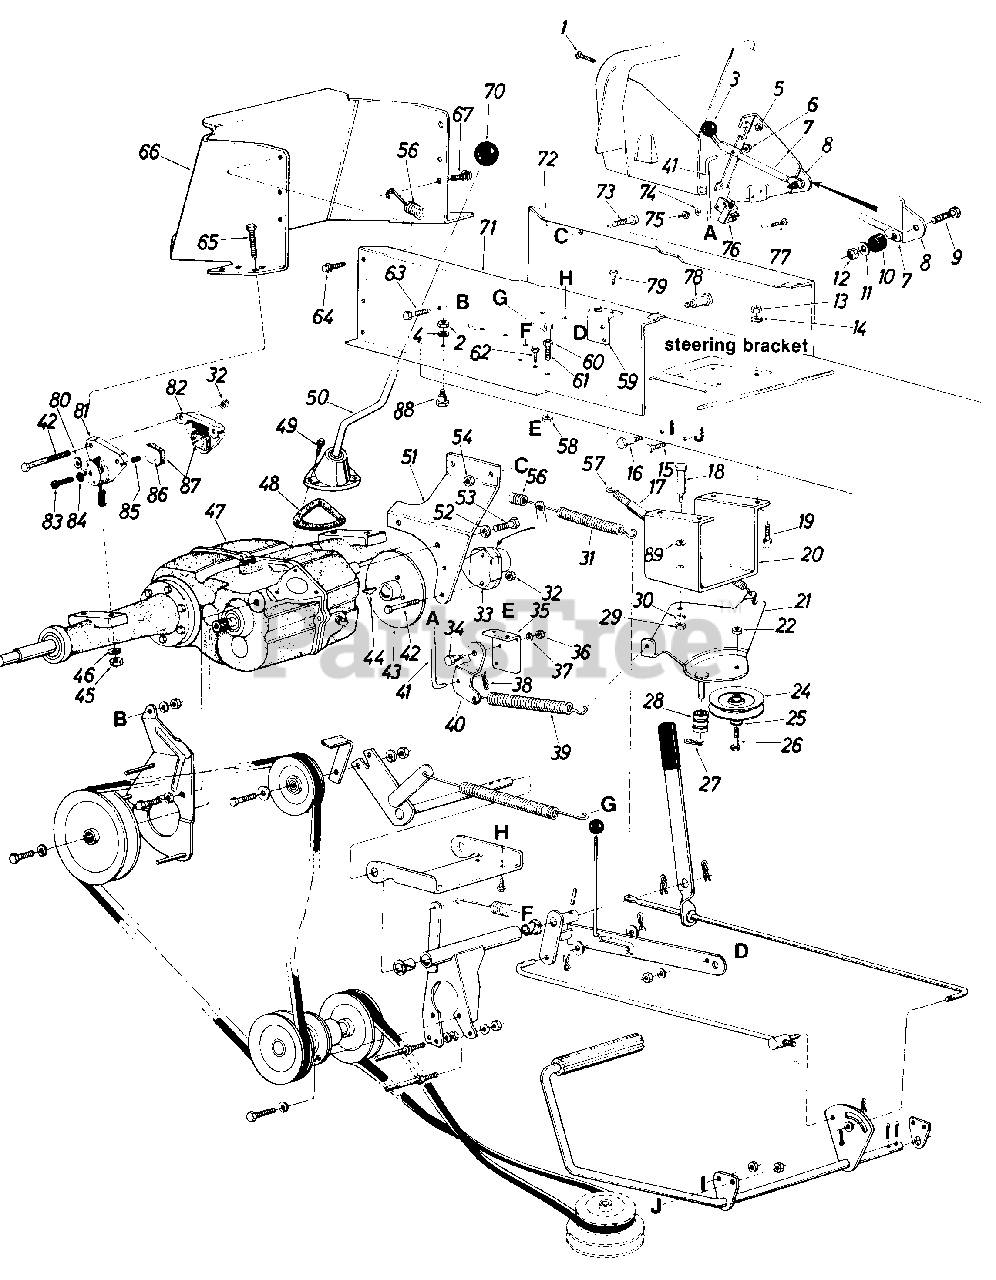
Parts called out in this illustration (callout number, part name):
1	Truss Mach. Scr. 1/4-20 x .50" Lg.
2	Hex Nut 1/4-20 Thd.
3	Knob Blade Clutch
4	LWash. 1/4 I.D.
5	Hex Sems Nut 1/4-20 Thd.
6	Push Cap 1/4" Rod
7	Blade Clutch Lever
8	Deck Clutch Control Brk't.
9	Hex Scr. 1/4-20 x 1.25" Lg.
10	Rubber Wash. .330 I.D. x .87
11	Fl-Wash. 1/4" I.D. x .75" O.D. x .057
12	Hex Cent. L-Nut 1/4-20 Thd.
13	Hex Nut 5/16-18 Thd.
14	L-Wash. 5/16" Scr.*
15	Hex Scr. 3/8-16 x .62" Lg.
16	Shld. Scr. 1/2" Dia. x .335 Lg. 3/8-16
17	Convoluted Conduit .50 I.D. x 4" Lg.
18	Shld. Scr. 7/16 Dia. x .16" 5/1 6-1 8
19	Hex Scr. 5/16-18 x 1.00" Lg.
20	Idler Mtg. Brk't. Deck
21	Idler Brk't. Ass'y.
22	Hex L-Nut 3/8-16 Thd.
24	4" "V" Idler Pulley
25	Fl-Wash. 3/8" I.D.
26	Hex Scr. 3/8-16 x 1.25" Lg.*
27	Hairpin Cotter 5/16" Rod
28	Spacer
29	Hex Nut 5/16-18 Thd.
30	L-Wash. 5/16" Scr.
31	Ext. Spring Brake Rod
32	Hex Cent. L-Nut 3/8-16 Thd.
33	Disc Brake Caliper Ass'y.
34	Shld. Scr. 7/16" Dia. x .16" Lg. 5/16-18
35	Parking Brake Cam Mtg. Brk't .
36	Hex Nut 5/16-18 Thd.
37	L-Wash. 5/16" Scr.
38	Hairpin Cotter 5/16" Dia.
39	Ext. Spring Deck Control
40	Deck Control Pivot Brk't.
41	Deck Control Rod
42	Hex Scr. 3/8-16 x 2.50" Lg.*
43	Hub & Disc Ass'y.
44	Hi-Pro Key 3/16 x 314" Lg.
45	Hex Nut 3/8-16 Thd.
46	L-Wash. 3/8 Scr.
47	Transaxle
51	Transaxle Support
52	L-Wash. 3/8" Scr.*
53	Hex Scr. 3/8-16 x .75" Lg.
54	Hex L-Nut 3/8-16 Thd.
56	Ext. Spring Brake Return
57	Ext. Spring Deck Idler Return
58	Hex L-Nut 5/16-18 Thd.
59	Parking Brake Cam Mtg. Brk't.
60	Hex Nut 5/16-18 Thd.
61	Hex Scr. 5/16-18 x 1.50" Lg.*
62	Hex Thd. Rolling Scr. 1/4-20 x .50" Lg.
63	Hex Scr. 3/8-16 x .75" Lg.
64	Hex AB-Tap Scr. 5/16 x .75"
65	Hex Scr. 3/8-16 x 1.50" Lg.
66	Hitch Plate
67	Hex Thd. Rolling Scr. 5/16-24 x .75" Lg.
70	Knob Transaxle
71	Side Panel Upper Frame R.H.
72	Side Panel Upper Frame L.H.
73	Hex Scr. 3/8-16 x .75" Lg.
74	Ext. L-Wash. #10 Scr.
75	Hex Nut #10-24 Thd.
76	Safety Switch
77	Truss Mach. Scr. #10-24 x .50" Lg.
78	Shld. Scr. 7/16" Dia. x .16" Lg. 5/16-18
79	Hex Thd. Rolling Scr. 1/4-20 x .50" Lg.
81	Housing with Lever & Pin
83	Pin, Adjuster
84	Nut
85	Pin, Actuator
86	Backing Plate
87	Lining
88	Shld. Bolt .375" Dia. x .180" Lg. 1/4-20 Thd.
89	Wave Washer
